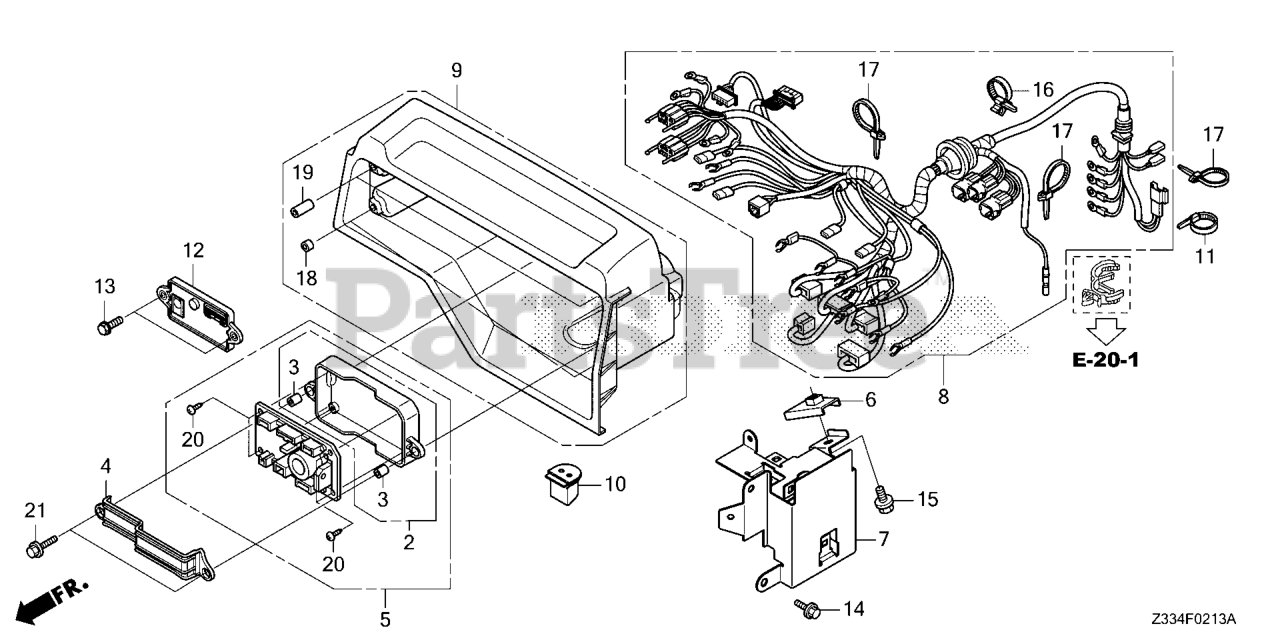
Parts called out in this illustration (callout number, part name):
1	REGULATOR UNIT, AUTOMATIC VOLTAGE (NOT AVAILABLE)
2	CASE, AUTOMATIC VOLTAGE REGULATOR (NOT AVAILABLE)
3	COLLAR, AUTOMATIC VOLTAGE REGULATOR CASE (NOT AVAILABLE)
4	COVER, AUTOMATIC VOLTAGE REGULATOR (NOT AVAILABLE)
5	CASE ASSY., AUTOMATIC VOLTAGE REGULATOR
5	COVER ASSY., AUTOMATIC VOLTAGE REGULATOR
6	STOPPER, HARNESS BASE
7	BASE, HARNESS CLIP
8	WIRE HARNESS ASSY., CONTROL (AG)
9	CASE, CONTROL PANEL *NH314* (CONDUCT GRAY)
10	DUCT, CONTROL CASE
11	TIE, CABLE (C)
12	SENSING UNIT (CO)
13	BOLT, FLANGE (5X14)
14	BOLT, FLANGE (6X12) (CT200)
15	BOLT, FLANGE (6X25) (TORX)
16	STRAP, CABLE (105MM) *NH1* (Honda Code 1685536). (BLACK)
17	TIE, CABLE
18	COLLAR, CONTROL CASE
19	COLLAR, CONTROL CASE
20	SCREW, TAPPING (4X10) (PO)
21	BOLT, FLANGE (6X16) Use from Engine SN 2056820.
